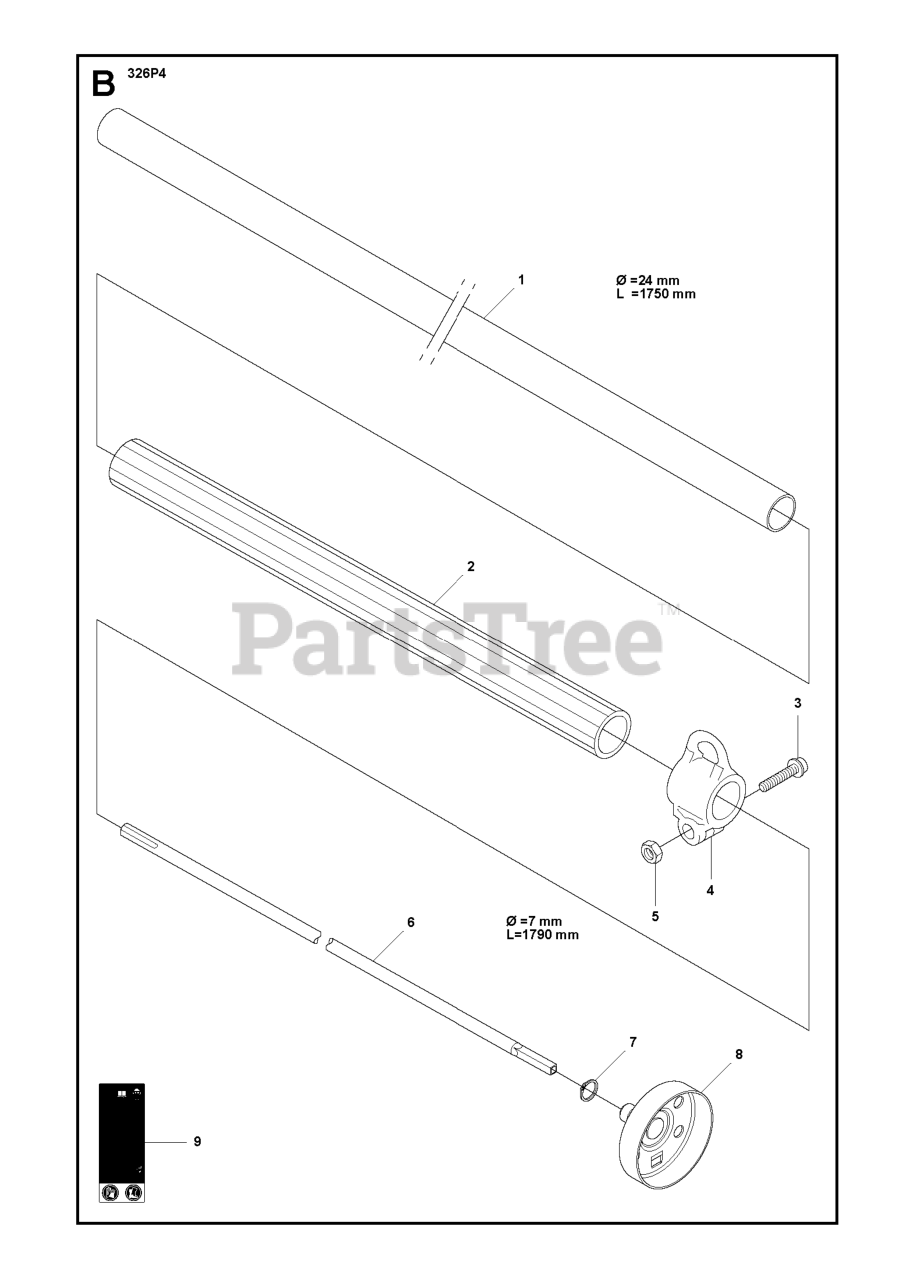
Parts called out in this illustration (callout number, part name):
1	TUBE
3	SCREW
4	HARNESS HOLDER
6	SHAFT P4
7	RETAINING RING SGA 10
8	CLUTCH DRUM
